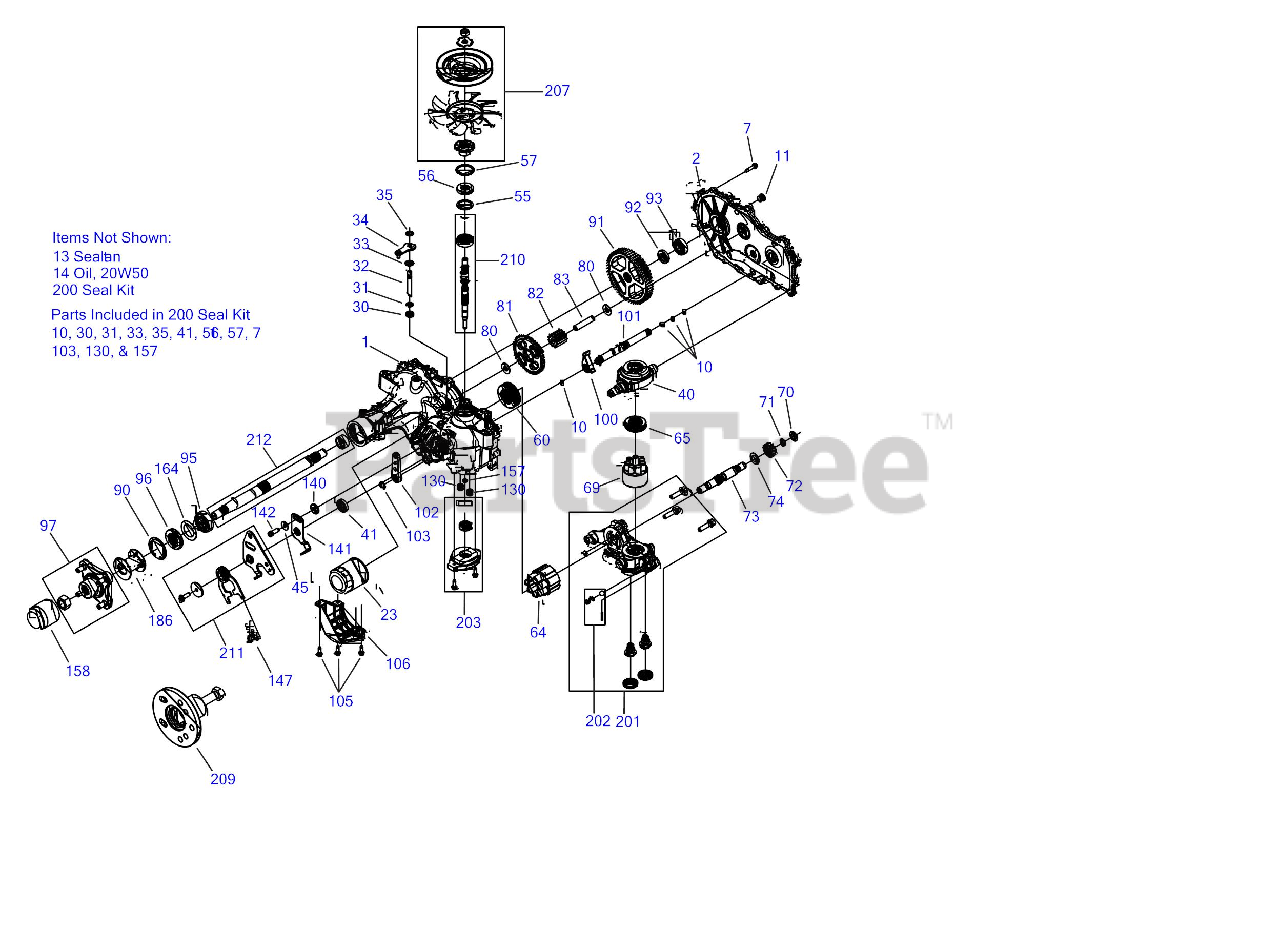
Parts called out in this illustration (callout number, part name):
1	Kit, Main Housing, RH Charge
2	Kit, Side Cover RH
7	Screw, Hex Washer
23	Filter, Spin-On 2.6 x 3.0
30	Seal, Lip, .375 x .75 x .25
31	Ring, Retaining .375 External
32	Rod, Bypass
33	Ring Retaining .750 Internal
34	Arm, Bypass
35	Ring, Ret .375 External
40	Trunnion, Swashplate
41	Seal, Lip 18 x 32 x 7
45	Washer, .34 x .88 x .06
55	Washer, 1.23 x 1.57 x .04
56	Seal, Lip 17 x 40 x 7
57	Ring Retaining Internal
60	Bearing, Thrust 35 x 62 x 18
64	Kit, 16cc Cylinder Block Assembly
65	Thrust Bearing, 30 x 52 x 13
69	Kit, Block, 7 Piston
70	Washer, .63 x 1.00 x .05
71	Ring, Reatining, Motor Shaft
72	Gear, 14T (Steel)
73	Shaft, Motor
74	Washer, .71 x 1.16 x .04
81	Gear, 45T
82	Gear, 11T (Steel)
83	Pin, Jackshaft
90	Ring, Retaining 2.25 Internal
91	Gear, 54T
92	Spacer, .750 x 1.00 x .257
93	Bearing, Ball 3/4 x 40mm x 12mm
95	Bearing, Ball 25.4 x 52 x 15
96	Seal, Lip, 1.0 x 2.06 x .38
97	Kit, Hub 4-Bolt
100	Pawl, Brake
101	Kit, brake Shaft
102	Handle, Actuating
103	Ring, Retaining, External .438
105	Screw, Hex Washer 1/4-20 x .75
106	Guard, Filter, RH
111	Kit, Fitting 1/2 Beaded 9/16 SAE
130	Tube, Charge Triple O-Ring
140	Spacer, .320 x 1.005 x .150
141	Arm, Neutral Right
142	SHCS, 5/16-24 x 7/8 (W/Patch)
147	Spring, Extension
157	Seal, Gerotor .281 x .420 x .160
158	Cap, Axle
164	Spacer, 1.355 x 2.035 x .021
186	Tube, Axle 2.03
200	Kit. Seal, ZT-2800
201	Kit, Center Section RH Charge
202	Kit, Charge Relief
203	Kit, Charge
207	Kit, Fan Pulley
207	Fan Only
207	Pulley Hub
209	Kit, Hub Puller
210	Kit, Input Shaft
211	Kit, RTN Bidirectional
212	Kit, Shaft Axle
